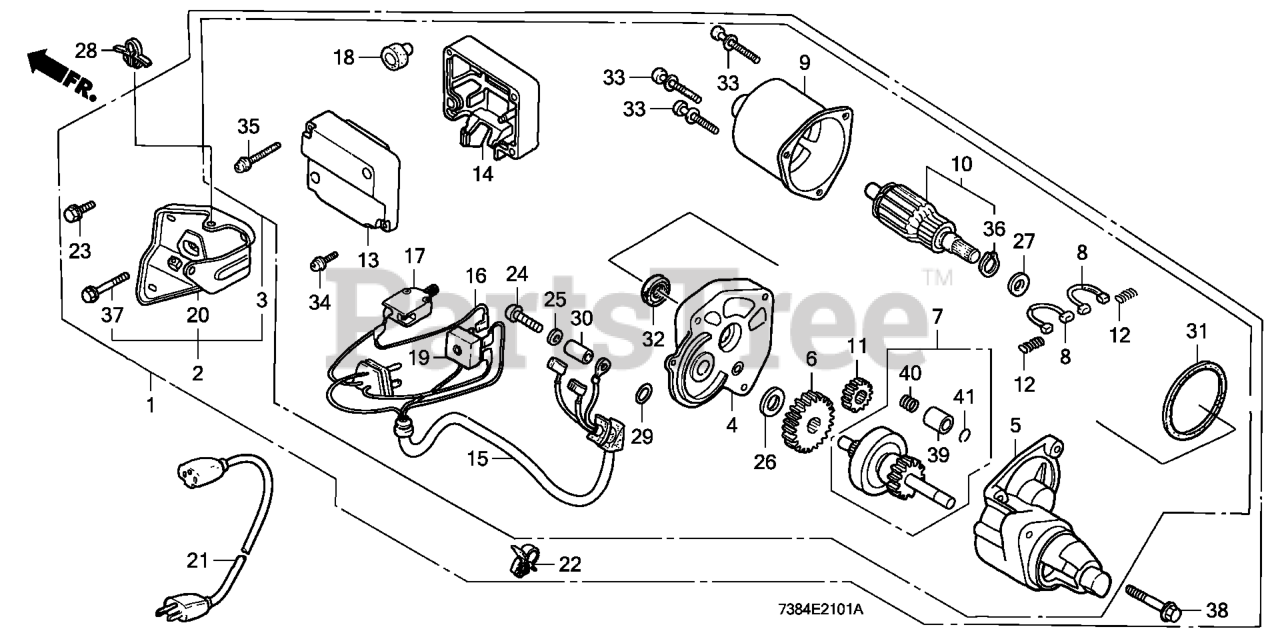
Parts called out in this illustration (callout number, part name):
1	STARTER KIT, SELF (A.C.) Use from Engine SN 1171449.
2	STARTER MOTOR ASSY. (A.C.)
3	MOTOR ASSY., STARTER (A.C.) Use from Engine SN 1171449.
4	HOUSING, CENTER Use from Engine SN 2056820.
5	HOUSING, PINION Use from Engine SN 1171449.
6	GEAR, REDUCTION Use up to Engine SN 2056819.
7	CLUTCH Use from Engine SN 1171449.
8	BRUSH Use from Engine SN 2056820.
9	YOKE Use from Engine SN 2056820.
10	ARMATURE Use from Engine SN 2056820.
11	GEAR, DRIVE Use up to Engine SN 2056819.
12	SPRING, BRUSH RETURN Use from Engine SN 2056820.
13	COVER Use from Engine SN 2056820.
14	CASE Use from Engine SN 2056820.
15	WIRE Use from Engine SN 2056820.
16	SUB-WIRE Use up to Engine SN 2056819.
17	SWITCH, STARTER (Honda Code 2299584). (A.C. 380V-16A)
17	SWITCH, STARTER (Honda Code 2773141). (A.C. 250V-16A)
18	CAP Use up to Engine SN 2056819.
19	DIODE Use up to Engine SN 2056819.
20	BRACKET, SWITCH BOX Use up to Engine SN 1171448.
21	WIRE, POWER Use up to Engine SN 2056819.
22	HOLDER, STOP SWITCH WIRE Use up to Engine SN 2056819.
23	BOLT, FLANGE (6X12) (CT200)
24	SCREW, TRUSS (4X30) Use from Engine SN 2056820.
25	WASHER, STAR (4MM) Use from Engine SN 2056820.
26	WASHER (A) Use from Engine SN 2056820.
27	WASHER (B) Use from Engine SN 2056820.
29	O-RING Use from Engine SN 2056820.
30	COLLAR Use from Engine SN 2056820.
31	GASKET Use from Engine SN 2056820.
32	OIL SEAL Use up to Engine SN 2056819.
33	SCREW-WASHER (5X30) Use up to Engine SN 2056819.
34	SCREW-WASHER (4X20)
35	SCREW-WASHER (4X30)
36	CIRCLIP (OUTER) (12MM) Use up to Engine SN 2056819.
37	BOLT, FLANGE (6X40)
38	BOLT, FLANGE (8X35)
39	STOPPER, PINION Use from Engine SN 2056820.
40	SPRING, COIL
41	RING, RETAINING Use from Engine SN 2056820.
